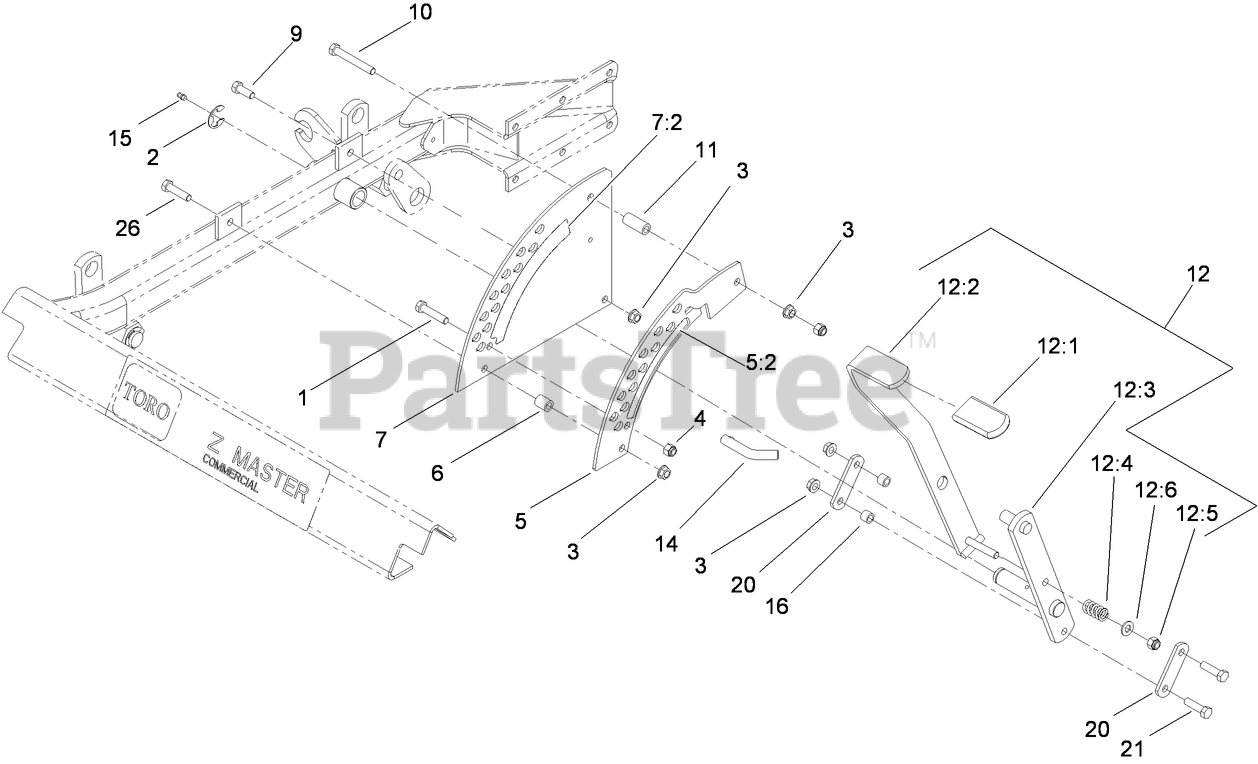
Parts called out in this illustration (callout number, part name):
1	SCREW-HH
2	RING-RETAINING, EXT
3	NUT-HHF, WHIZ
4	NUT-LOCK, NI
5	PLATE-HOC, INNER
5:2	DECAL-DECK HEIGHT, INNER
6	BUSHING-LEVER, LIFT
7	PLATE-HOC, OUTER
7:2	DECAL-DECK HEIGHT, OUTER
9	SCREW-HH
10	SCREW-HH
11	BUSHING-LEVER, LIFT
12	DECK LIFT HANDLE ASM
12:1	GRIP-LEVER, LIFT
12:2	HANDLE-LIFT
12:3	LIFT ARM ASM
12:4	SPRING-COMPRESSION
12:5	NUT-LOCK, NI
12:6	WASHER-FLAT
14	PIN-HOC
15	FITTING-GREASE
16	Bushing
20	ARM-LIFT, DECK
21	SCREW-HH
26	SCREW-HH
